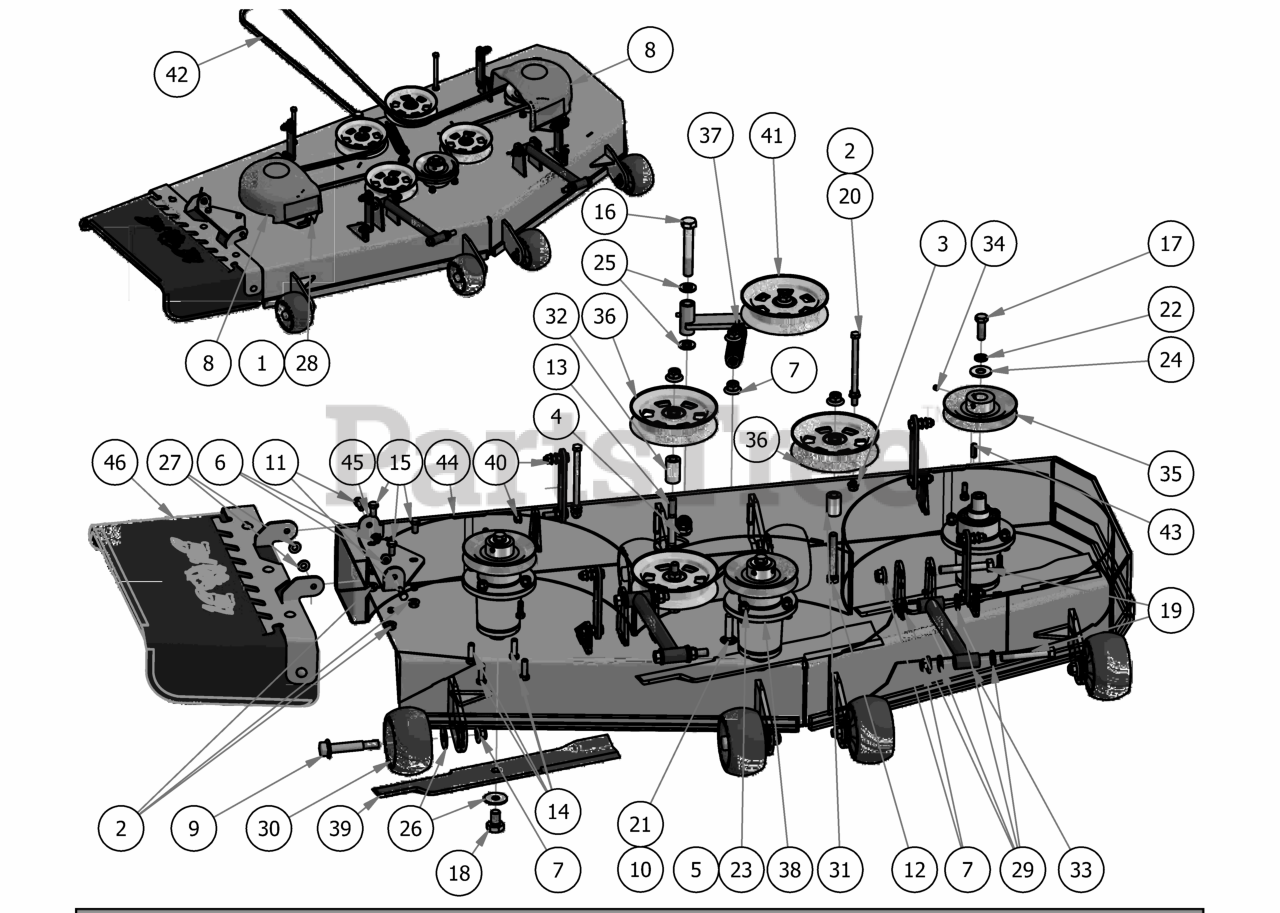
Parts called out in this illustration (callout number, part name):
1	Acorn nut-pulley Cover
2	3/8" Flange Nut
3	3/8" Nylock Flange Nut
4	5/8-11 Nylon Insert Jam Half Nut
5	3/8" Hex Nut
6	5/16" Nylon Flange Nut
7	1/2-13 Nylon Flange Nut
8	Pulley Cover
9	Deck Wheel Bolt
10	1/2 x 2" Carriage Bolt
11	5/16-18 x 1 GR 5 Hex Bolt Zinc
12	1/2 x 3 1/2 Flange Bolt Grade 8
13	1/2" x 4" Bolt (Grade 8)
14	3/8" x 1 1/4" Hex Bolt
15	3/8" x 3/4" Hex Bolt
16	5/8" x 4" Hex Bolt
17	1/2"-20 x 1 1/2 - Grade 5 Fine Thread Bolt
18	5/8" x 1 1/2" Grade 8 Hex Bolt (Fine)
19	1/2-13 x 3 1/2 GR 5 Hex Bolt
20	3/8-16 x 5 1/2 Hex Bolt
21	.517 Square Hole Round Washer
22	1/2" Lock Washer
23	3/8" Lock Washer
24	5/8'' Flat Washer
25	.630 ID Plastic Washer
26	1/2" Belleville Washer
27	.360 ID Plastic Washer
28	.360 ID Plastic Washer-Black
29	.505 Nylon Spacer
30	Deck Wheel
31	Idler Pulley Standoff
32	1 3/4" Pulley Spacer
33	MZ/ZT Deck Locator
34	5/16 Set Screw
35	5.25" Deck Spindle Pulley
36	5-3/4 Idler Pulley
37	Deck Idler Spring
38	Spindle Assembly
39	54" Deck Fusion Blade For Outlaw
40	Deck Hanger Assembly
41	2017 54"/48" Deck Idler Assembly
42	B155.75 Deck Belt
43	1/4" x 1" Key
44	54 ZT Welded Deck Shell
45	Discharge Chute Hanger (deck mounted)
46	Discharge Chute Assembly
